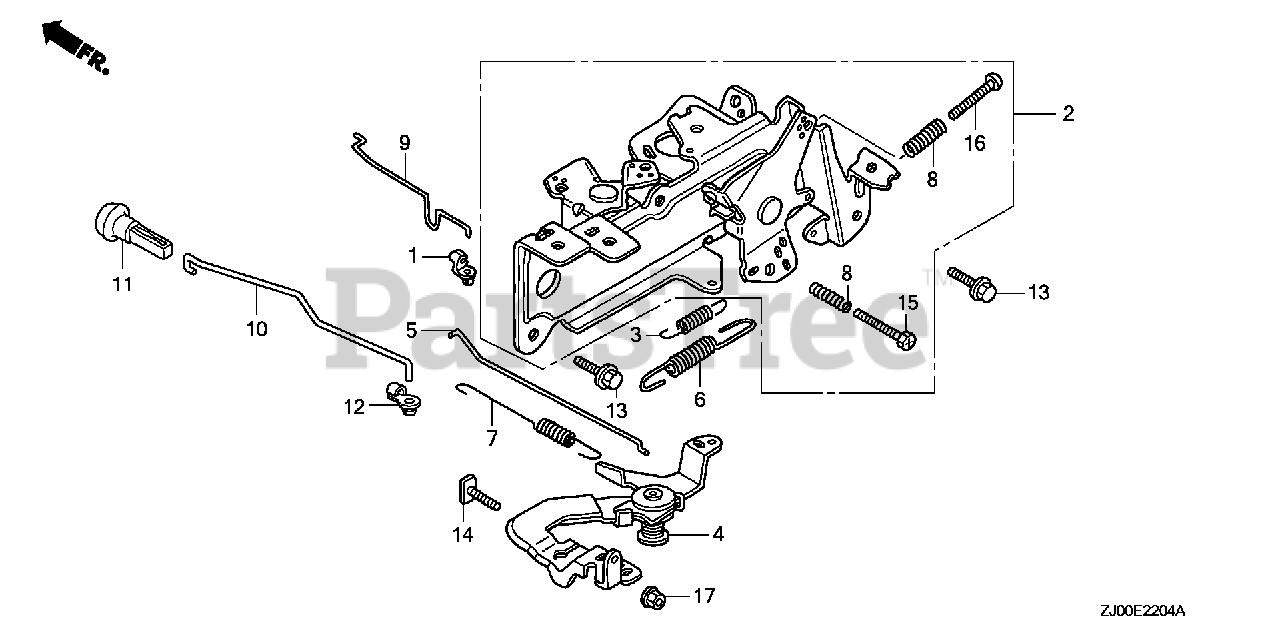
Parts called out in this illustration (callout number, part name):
1	JOINT, ROD
2	CONTROL ASSY. (AUTO THROTTLE)
3	SPRING, STARTER
4	ARM, GOVERNOR
5	ROD, GOVERNOR
6	SPRING, GOVERNOR (MANUAL)
7	SPRING, THROTTLE RETURN
8	SPRING, CONTROL ADJUSTING
9	ROD, CHOKE CONTROL
10	ROD, CHOKE KNOB
11	KNOB, CHOKE
12	BUSH, LINKAGE
13	BOLT, FLANGE (6X14) (CT200)
14	BOLT, GOVERNOR ARM
15	BOLT, RECESSED (5X25)
16	SCREW, PAN (5X35)
17	NUT, FLANGE (6MM)
